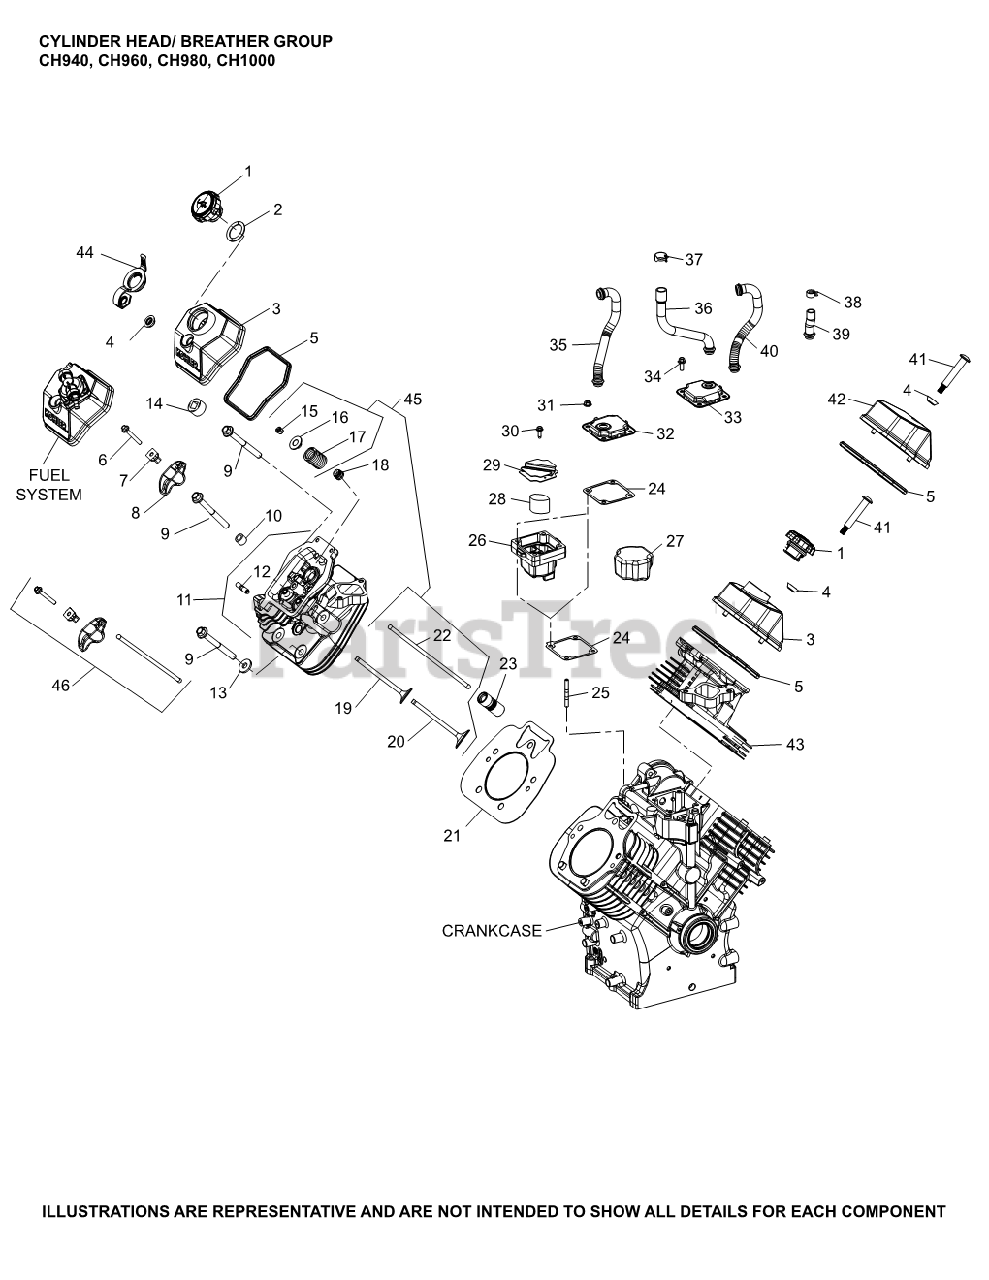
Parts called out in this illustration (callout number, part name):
1	CAP ASSEMBLY
3	KIT, COVER, VALVE (OIL FILL)
4	GROMMET, VALVE COVER SCREW
5	SEAL, VALVE COVER-USE 62 032 20-S
6	SCREW, FLG M6X1.0X45
7	PIVOT, ROCKER ARM
8	ARM, ROCKER
9	SCREW, FLG M10X1.5X90
11	HEAD CYLINDER #2
13	WASHER, FLAT 13/32"
14	PLUG, PIPE 3/4 NPTF SQ CTSK USE 25 139 89-S
15	KIT, RETAINER
16	CAP, VALVE SPRING
17	SPRING, VALVE
18	SEAL, VALVE BAND
19	VALVE, EXHAUST
20	VALVE, INTAKE
21	KIT, CYLINDER HEAD GASKET
22	ROD, PUSH
23	LIFTER, VALVE HYDRAULIC - (#2535111S)
24	GASKET, BREATHER
27	FILTER, BREATHER
33	KIT, BREATHER ASSEMBLY
34	SCREW, THREAD FORMING
40	HOSE, BREATHER H/S
41	SCREW, SHOULDER
43	HEAD CYLINDER #1
